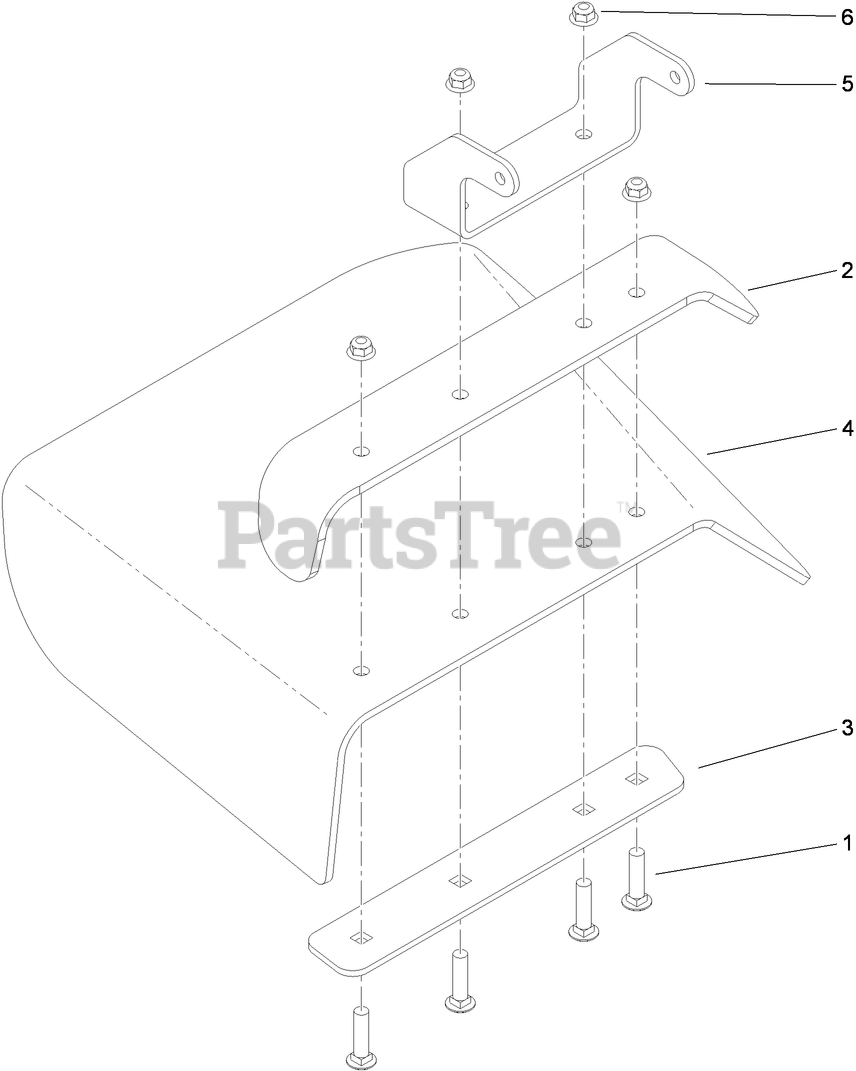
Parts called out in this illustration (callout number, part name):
1	SCREW-CARR
2	DEFLECTOR
3	STRAP-DISCHARGE
4	DEFLECTOR-RUBBER
5	BRACKET-MOUNTING, DEFLECTOR
6	NUT-HF, NI
